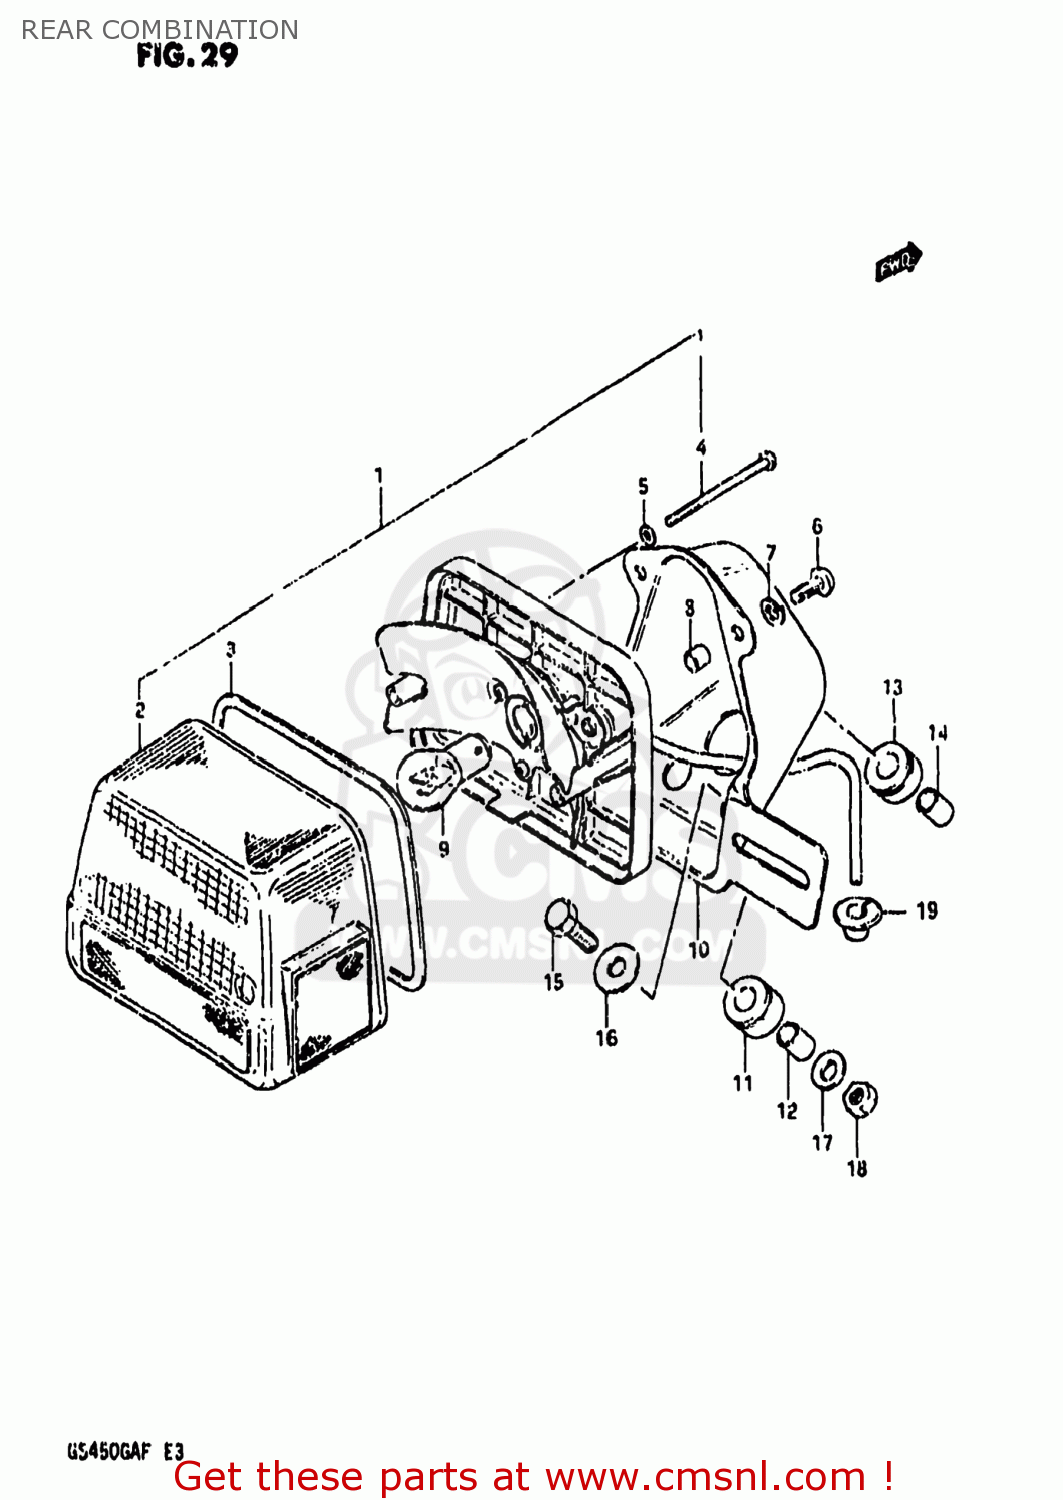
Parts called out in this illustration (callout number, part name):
1	LAMP UNIT,RR COMBNATION
2	LENS
3	GASKET (NAS)
4	SCREW
5	GASKET (NAS)
6	SCREW
7	LOCK WASHER
8	SPACER
9	BULB(12V23W)
10	BRACKET,REAR COMBINATION LAMP
11	CUSHION,REAR COMBINATION LAMP
12	SPACER,REAR COMBINATION LAMP
13	CUSHION
14	SPACER
15	BOLT
16	WASHER (6.5X20X1.2)
17	WASHER, LOWER
18	NUT
19	GROMMET
